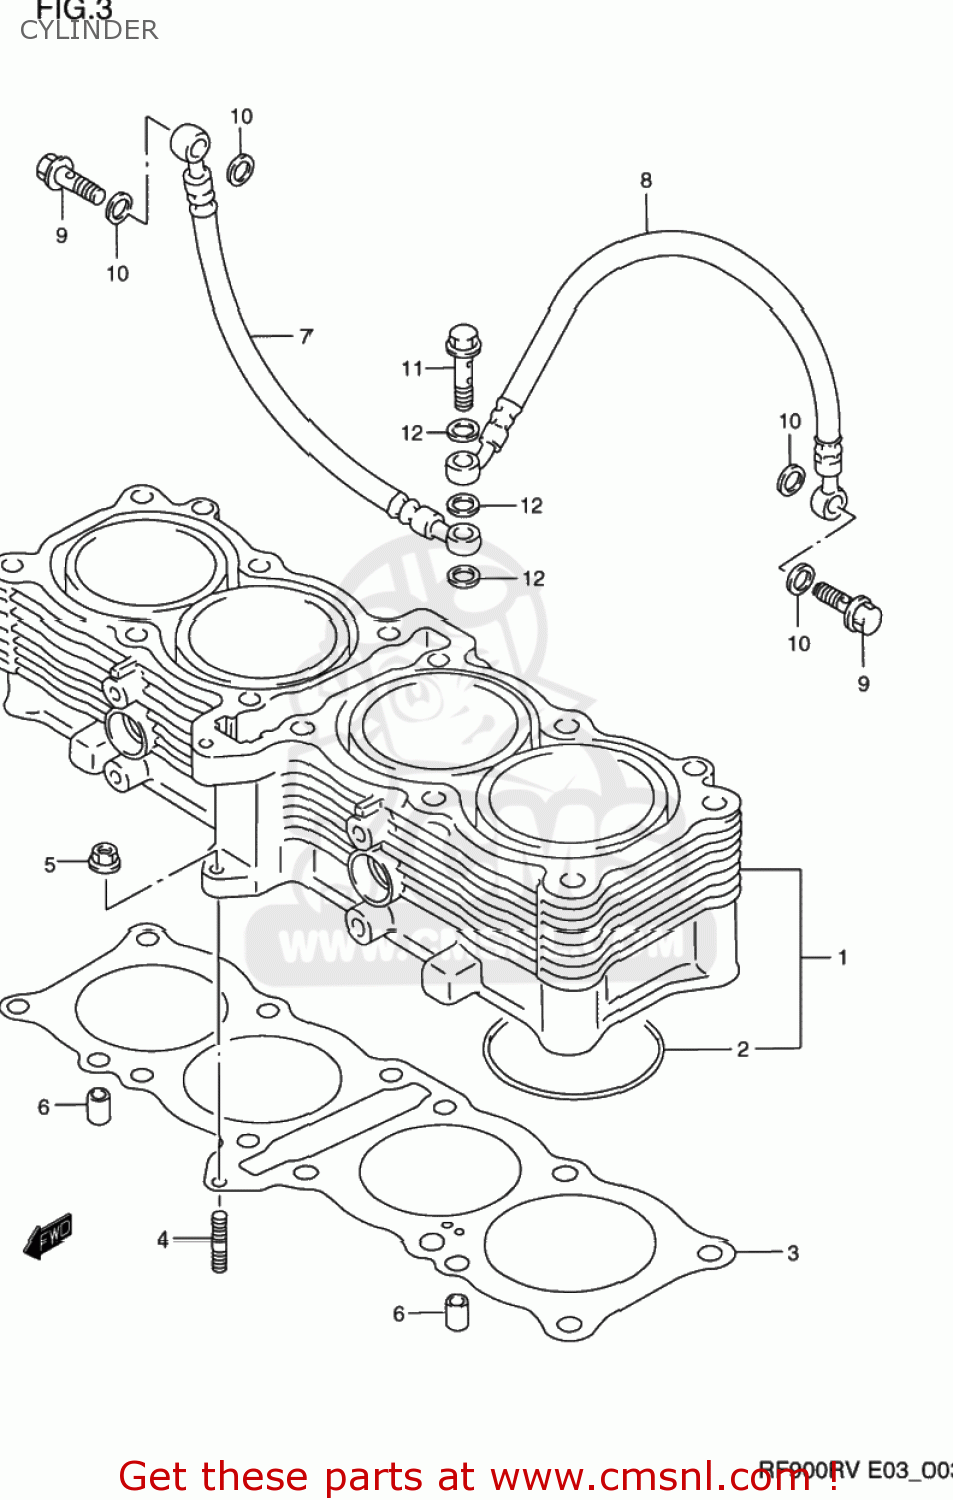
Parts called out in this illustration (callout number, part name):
1	CYLINDER COMP
2	O RING(D:2.6,ID:69.6)
3	GASKET,CYLINDER
4	STUD,M6X1X32
5	NUT
6	PIN
7	HOSE,CYLINDER HEAD OIL,R
8	HOSE,CYLINDER HEAD OIL,L
9	BOLT,OIL PIPE UNION,NO
10	GASKET(8.2X14X1) (NAS)
11	BOLT,OIL PIPE UNION,NO
12	WASHER(10X15X1.5)
